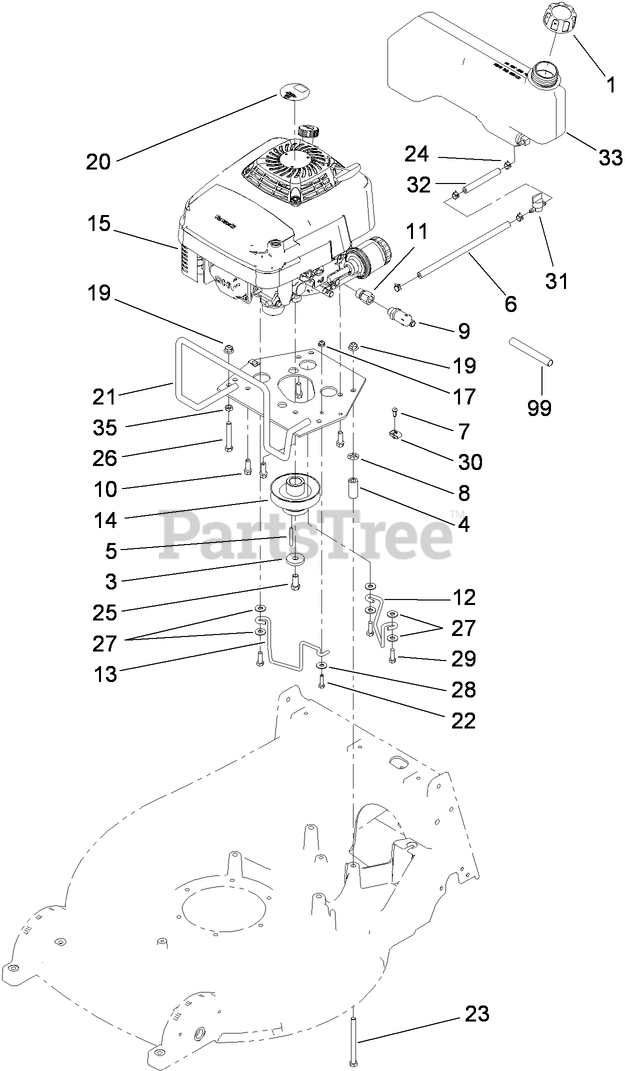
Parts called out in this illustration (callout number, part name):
1	CAP-GAS
3	WASHER-CLUTCH
4	SPACER
5	KEY-SQUARE
6	Hose-Fuel
7	SCREW
8	RING-RETAINING
9	VALVE-DRAIN, OIL
10	SCREW-TAPTITE
11	Adapter
12	GUIDE-BELT, REAR
13	GUIDE-BELT, FRONT
14	SHEAVE-DRIVE
15	ENGINE-Kawasaki, FJ180V-AS64
17	NUT-HF
19	NUT-HF, NI
21	PLATE-ENGINE
22	SCREW-HH
23	SCREW-HH
24	CLAMP-HOSE
25	SCREW-HH
26	SCREW-HH
27	WASHER-FLAT
28	WASHER-BELLEVILLE
29	SCREW-HH
31	VALVE-FUEL
32	HOSE-FUEL
33	FUEL TANK ASM
35	NUT-JAM
99	HOSE-DRAIN, OIL
